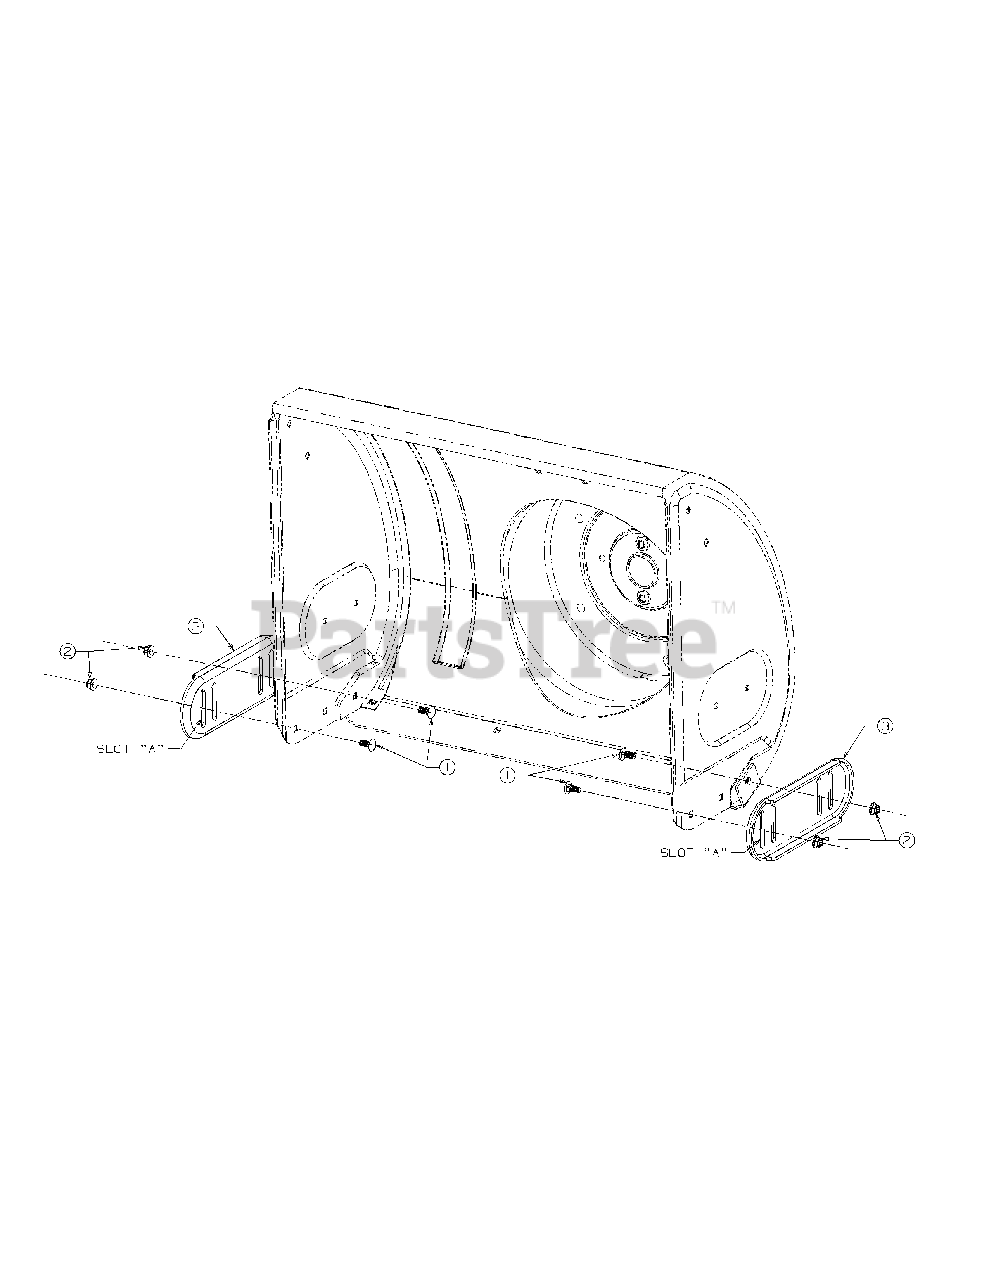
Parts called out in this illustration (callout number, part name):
1	Carriage Bolt 5/16-18 X .75
2	Nut-Flglk 5/16-18
3	Slide Shoe steel
3	Polymer Reversible Shoe Kit
